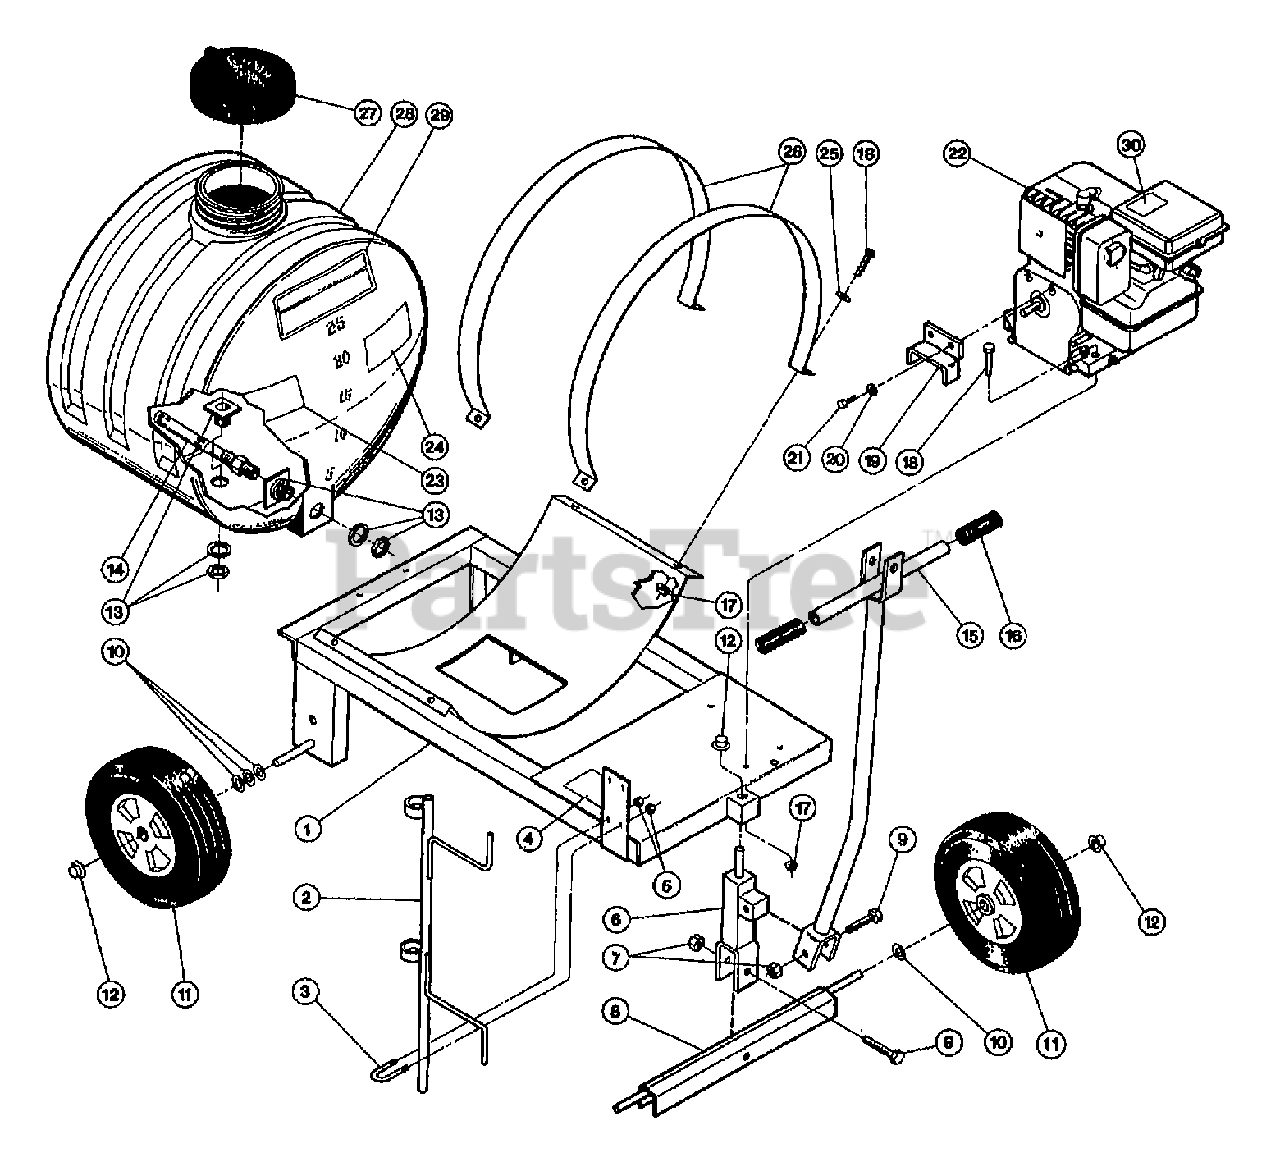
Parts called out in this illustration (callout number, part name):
1	ASSM-UNDERCARRIAGE
2	ASSM-GUN/HOSE STAND
3	BOLT-U 1/4X1X3/4 SPRAYER
4	DECAL-SAVE
5	NUT-HEX 1/4-20 ZP
6	ASSM-AXLE PIVOT FRONT
8	ASSM-FRONT AXLE SPRAYER
9	SCR-HH 5/8-11X2.25 G5 ZP
10	WASHER-1.75X.625X.11
11	ASSM-TIRE/WHEEL 11592
12	NUT-PUSH 5/8
13	ASSM-BULK HEAD W21254002
14	AGITATOR-JET W33710019
15	ASSM-TOW HANDLE W/O GRIPS
16	HANDLEGRIP-25 GAL SPRAYER
17	NUT-HFLK 5/16-18 ZP
18	SCR-HH 5/16-18X1.5 G5 ZP
19	COVER-DRIVESHAFT SPRAYER
20	WASHER-LK .312 ZP
21	SCR-GRD 5 W02050502FP
22	ENGINE, 3HP BRIGGS & STRATTON #80232
23	DECAL-DANGER AVOID W2045146
24	DECAL-ENG SPEED W2045149
25	WASHER-FLAT 5/16 SAE
26	STRAP-TANK SECURING
27	CAP-TANK W21254503
28	ASSM-TANK 25 GAL W/DECALS
29	DECAL-LOGO 25 GAL SPRAYER
30	DECAL-HOT SURFACE
